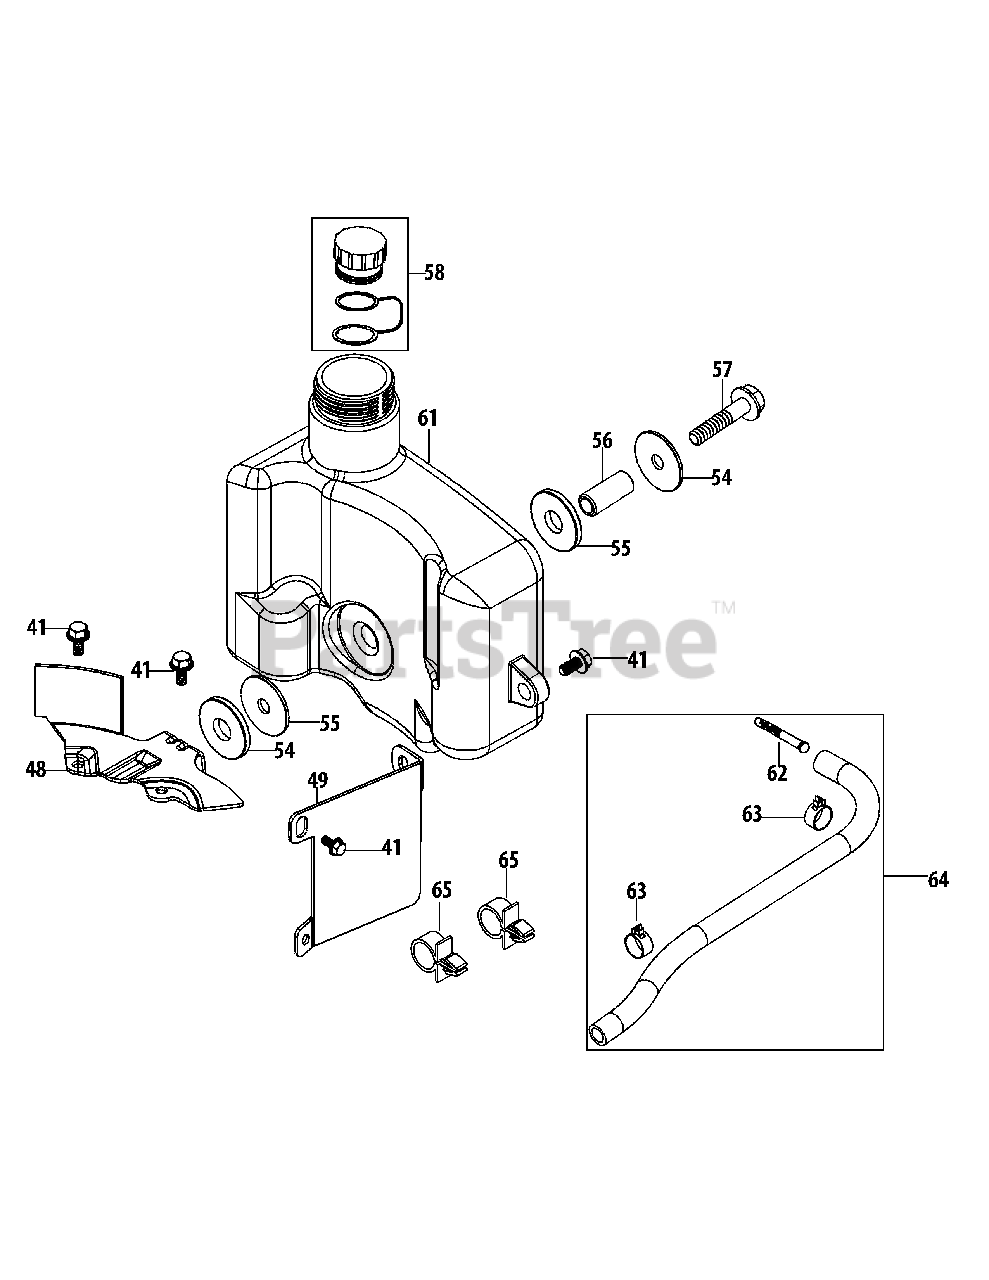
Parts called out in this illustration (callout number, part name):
41	Bolt M6X14 Multi-Purpose
48	Fuel Tank Bottom Bracket
49	Fuel Tank / Label Bracket
54	Fuel Tank Washer
55	Rubber Bushing
56	Fuel Tank Bushing
57	Bolt M8X50
58	Fuel Cap Assembly
61	Fuel Tank Assembly
62	Fuel Filter
63	Fuel Hose Clamp
64	Fuel Line Kit
65	Plastic Support Clamp
